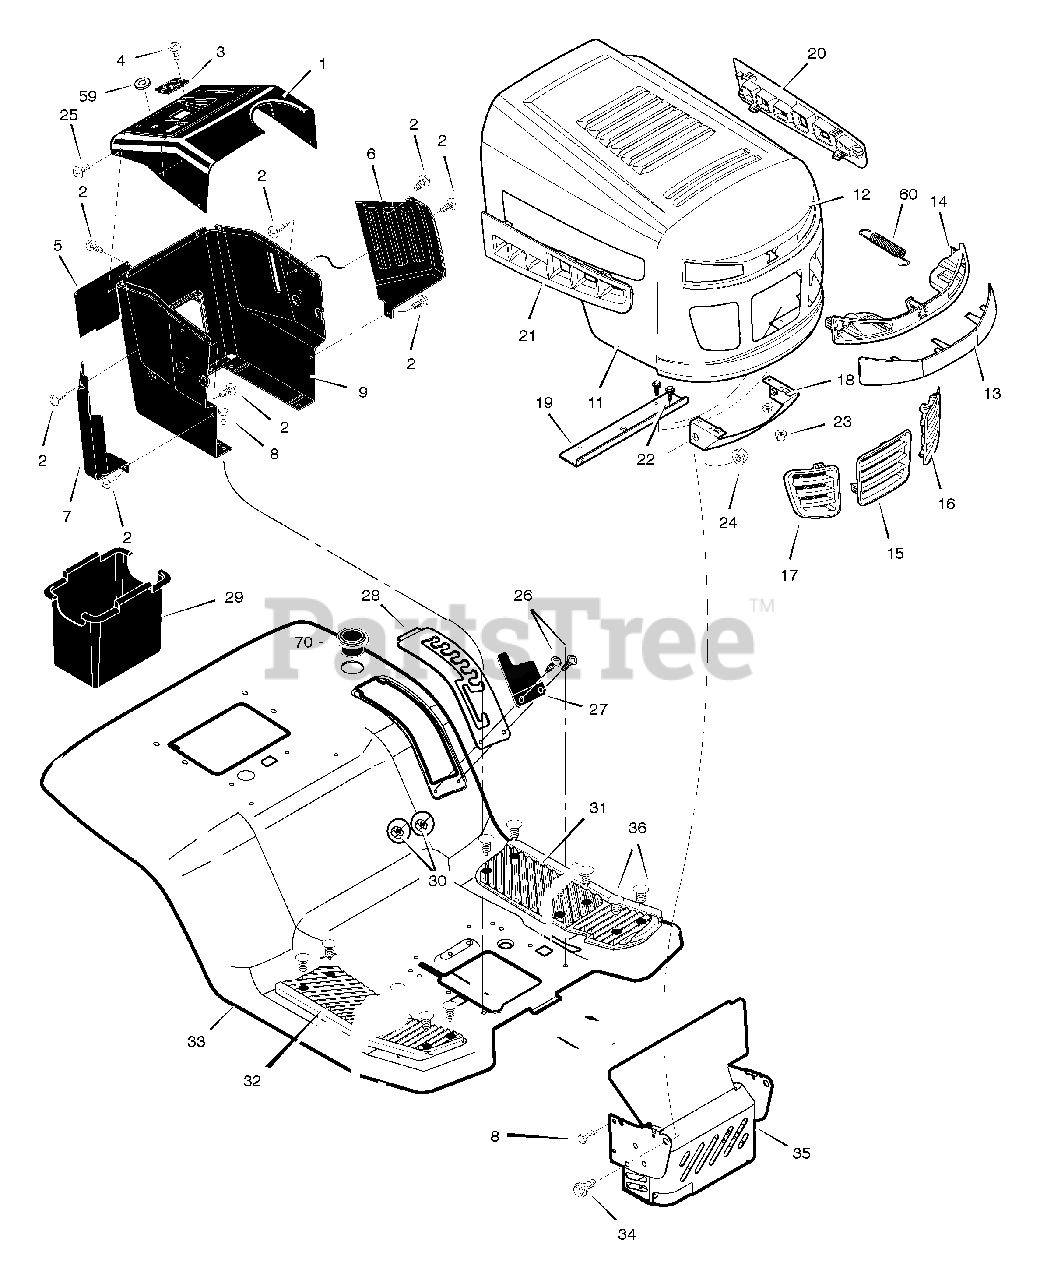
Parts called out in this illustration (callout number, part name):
2	Screw
3	Bearing, Upper Steering
5	Panel, Access
6	Panel, Left Side
7	Panel, Right Side
9	Support, Dash
11	Hood
12	Grille
14	Housing, Light
15	Insert, Center
16	Insert, Left
17	Insert, Right
18	Bracket, Lower Pivot
19	Bracket, Support
20	Insert, Left Hood
21	Insert, Right Hood
23	Nut
26	Bolt, Shoulder
28	Plate, Lift Detent
29	Container, Battery
31	Mat, Left
32	Mat, Right
33	Deck, Seat
34	Bolt
35	Shield, Heat
36	Fastener, Panel - Black
59	Grommet, Parking Brake
70	Holder, Beverage
